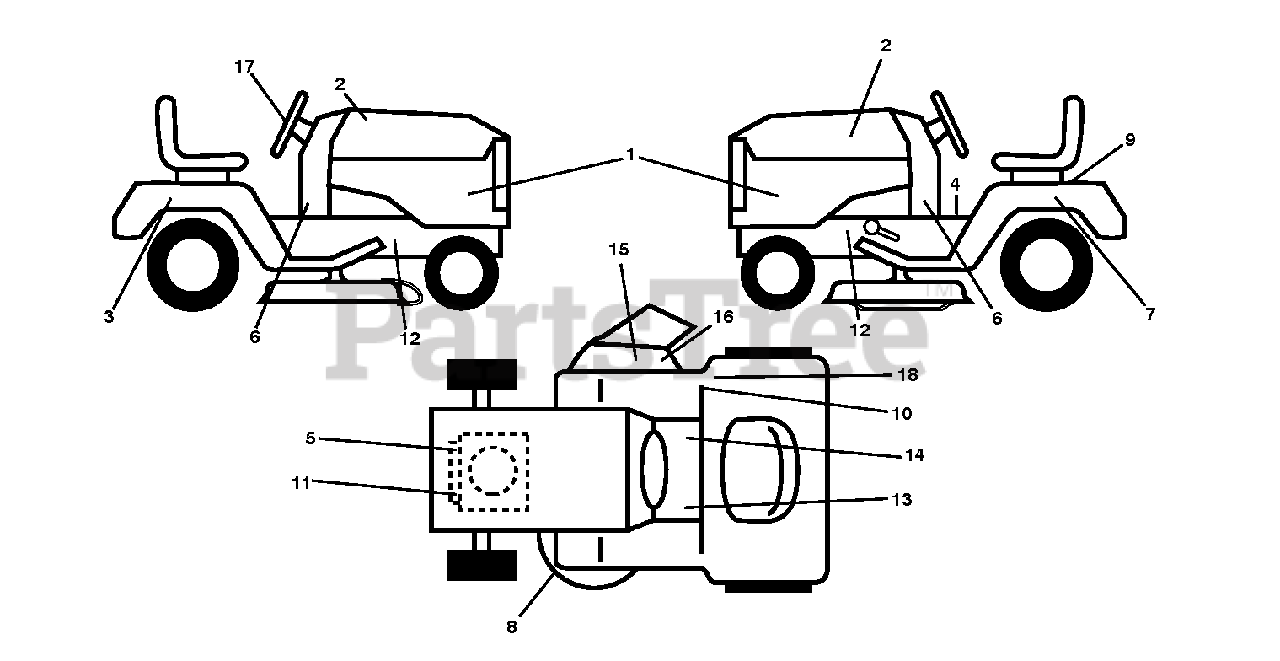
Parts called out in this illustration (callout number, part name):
6	DECAL.CHAS.TURBO
8	DECAL V BELT SCHEMATIC
9	DECAL BTRY SYMBOLS
10	DECAL 80 DBA
14	DECAL PARK BRAKE
15	DECAL.INTERNATIONL.CUTFINGER
16	DECAL, DEFLECT WARNING
